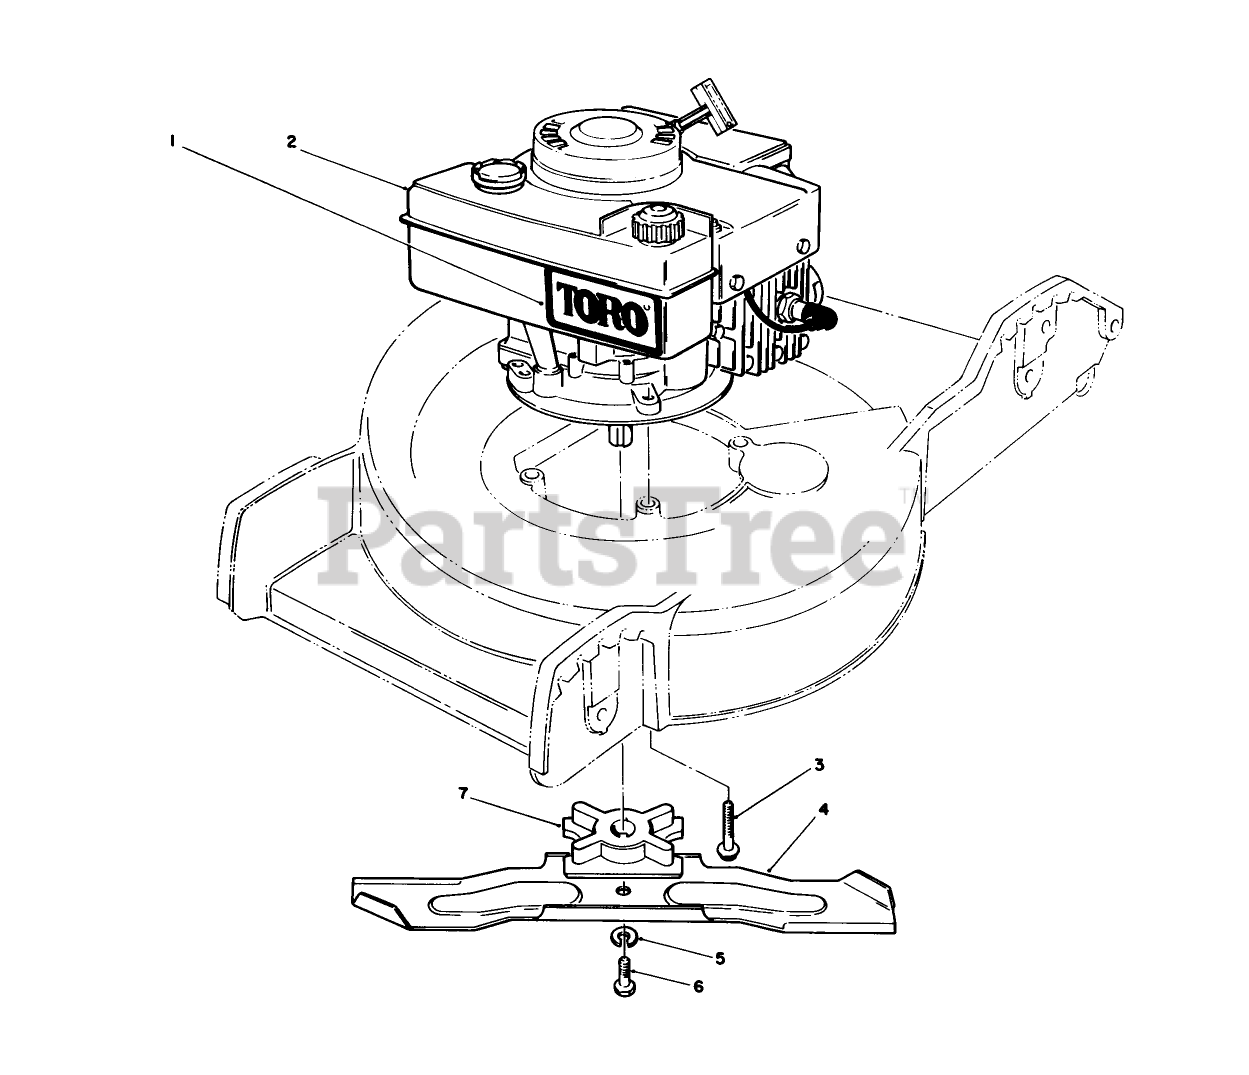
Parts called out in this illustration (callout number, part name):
1	Decal Tow
3	3/8-16 X 2 CAPSCREW
4	Blade
5	WASHER-LOCK
6	SCREW-HH
7	BLADE RETAINER
